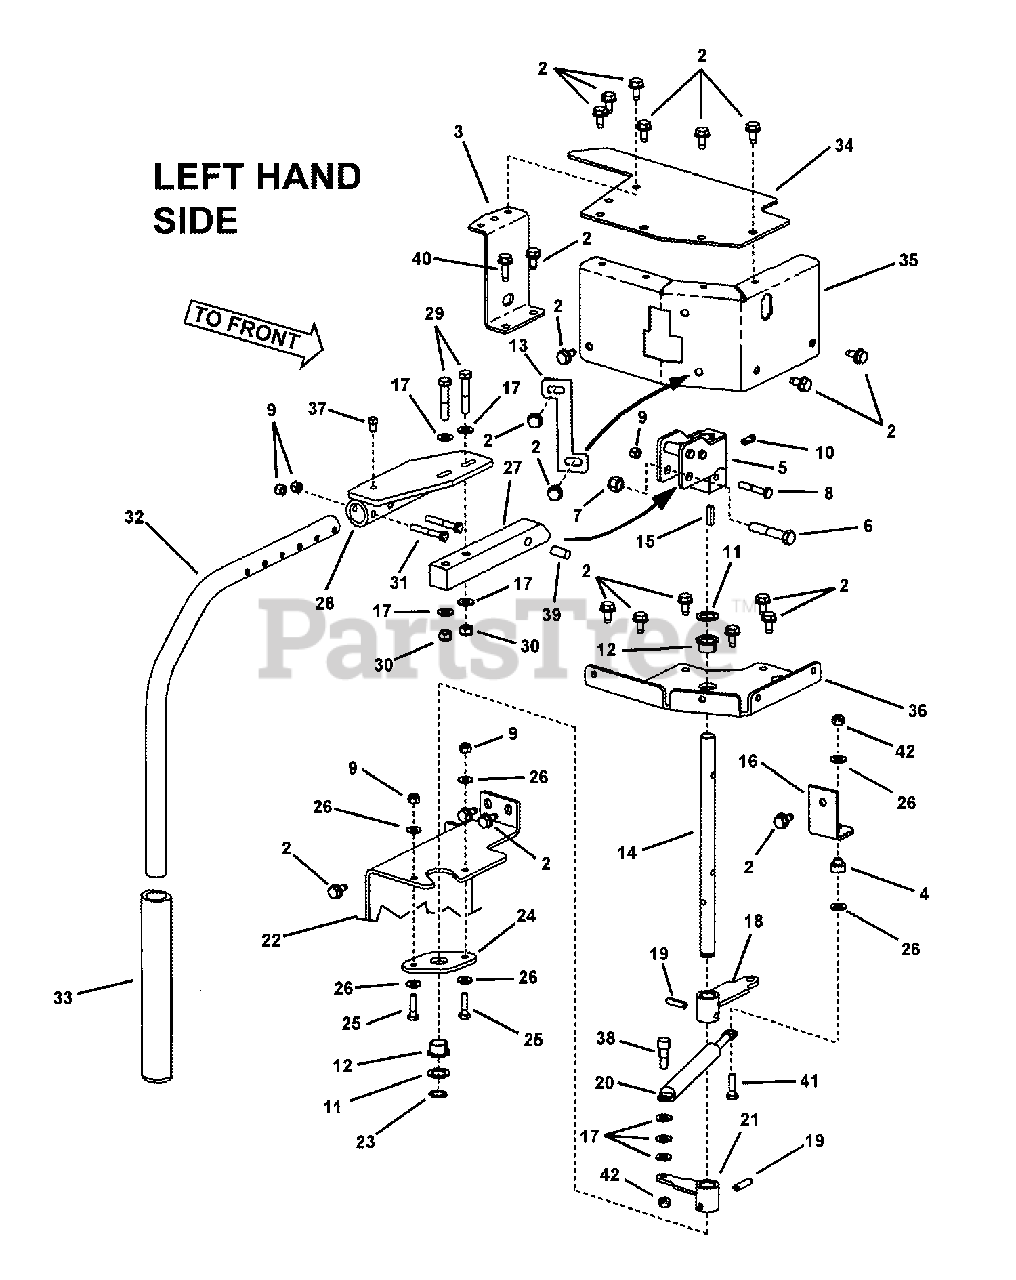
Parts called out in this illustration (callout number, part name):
2	SCREW, 5/16-18 x 5/8" Hex Washer Self-Tap
3	LIMITER BRACKET, Rear
4	SPACER
5	WELDMENT, Mounting Hub
6	BOLT, 3/8-16 X 2, GD5, CZ
7	NUT, 3/8-16 HEX NYLON LOCK
8	SCREW, 1/4-20 x 1-1/2" Hex Head Cap GR5
9	NUT, 1/4-20 HEX NYLON LOCK
10	SET SCREW, 5/16-18 Square Head w/Patch
11	WASHER, .64 I.D. x .99 O.D. x .05 Flat
12	BUSHING, Teflon Impregnated
13	BRACKET, Speed Control
15	KEY, 3/16" Square x 7/8" Long
16	BRACKET, Dampener Frame
17	WASHER, 5/16" Flat
18	WELDMENT, Bellcrank, Pump Control
19	GROOVE PIN, 1/4 x 1-1/4" long
20	CYLINDER, Dampener
21	WELDMENT, Bellcrank Dampener Control
22	CHANNEL, Mounting
23	RING, 5/8" External Retaining
24	MOUNTING PLATE, Left Hand Bearing
25	BOLT, 1/4-20 X 1" GD5 CZ
26	WASHER, .28 I.D. x .63 O.D. x .06 Thick Flat
27	MOUNTING ARM
28	WELDMENT, L.H. Adjustable Handlebar Attachment
29	BOLT, 5/16-18 X 1-3/4 GD5 YZ
30	NUT, 5/16-18 HEX NYLON LOCK
31	BOLT, 1/4-20 X 1-3/4" GD5 YZ
32	HANDLEBAR
33	GRIP, Twin Stick
34	LIMITER BRACKET, Left Hand Outside
35	LIMITER BRACKET, Left Hand
36	BUSHING MOUNTING PLATE, Left Hand
37	SET SCREW, 5/16-18 x 1/2" Square Head Cup Point w/patch
38	SCREW, 1/4-20 Shoulder Socket Head
39	SPACER, .498 O.D. x 1.010" long
40	SCREW, 5/16-18 x 1" Hex Washer Self-Tap
41	SCREW, 1/4-20 x 1-1/4" Hex Head Cap
42	NUT, 1/4-20 Hex Center Lock
